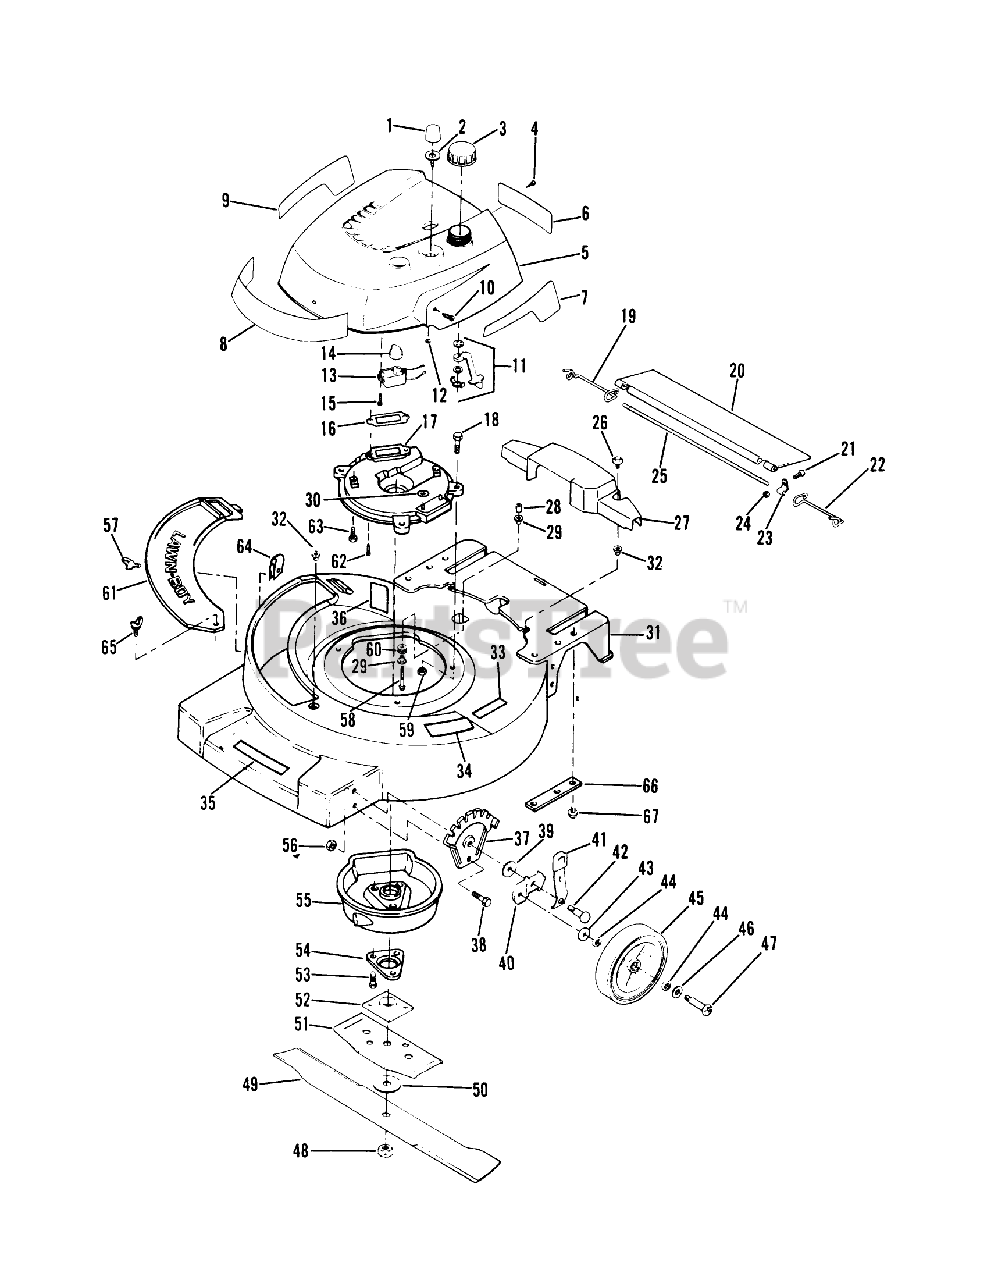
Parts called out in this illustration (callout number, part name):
4	SCREW S
10	SCREW S
12	LOCKNUT S
17	PLATE,MUFFLER F
18	SCREW
19	SPRING;TRAILING SHIELD RH
22	SPRIG T/SHLD ASOC
24	LOCKNUT E
26	SCREW SEMS TRM HEX HD
28	SPACER
29	SPACER ECK PRES
34	PAD FOOT
39	WASHER
41	KNOB & SPRING
43	WASHER WROUGHT
44	WASHER
45	WHEEL & TIRE KIT
46	SPACER
47	BOLT WHEEL
48	NUT-BLADE
50	WASHER
52	PLATE AND COLLAR ASM
53	SCREW
54	SUPPORT F
56	LOCKNUT
59	NUT-LOCK F
61	PLATE
62	SCREW V
65	WING SCREW LAWRE
67	SCREW
